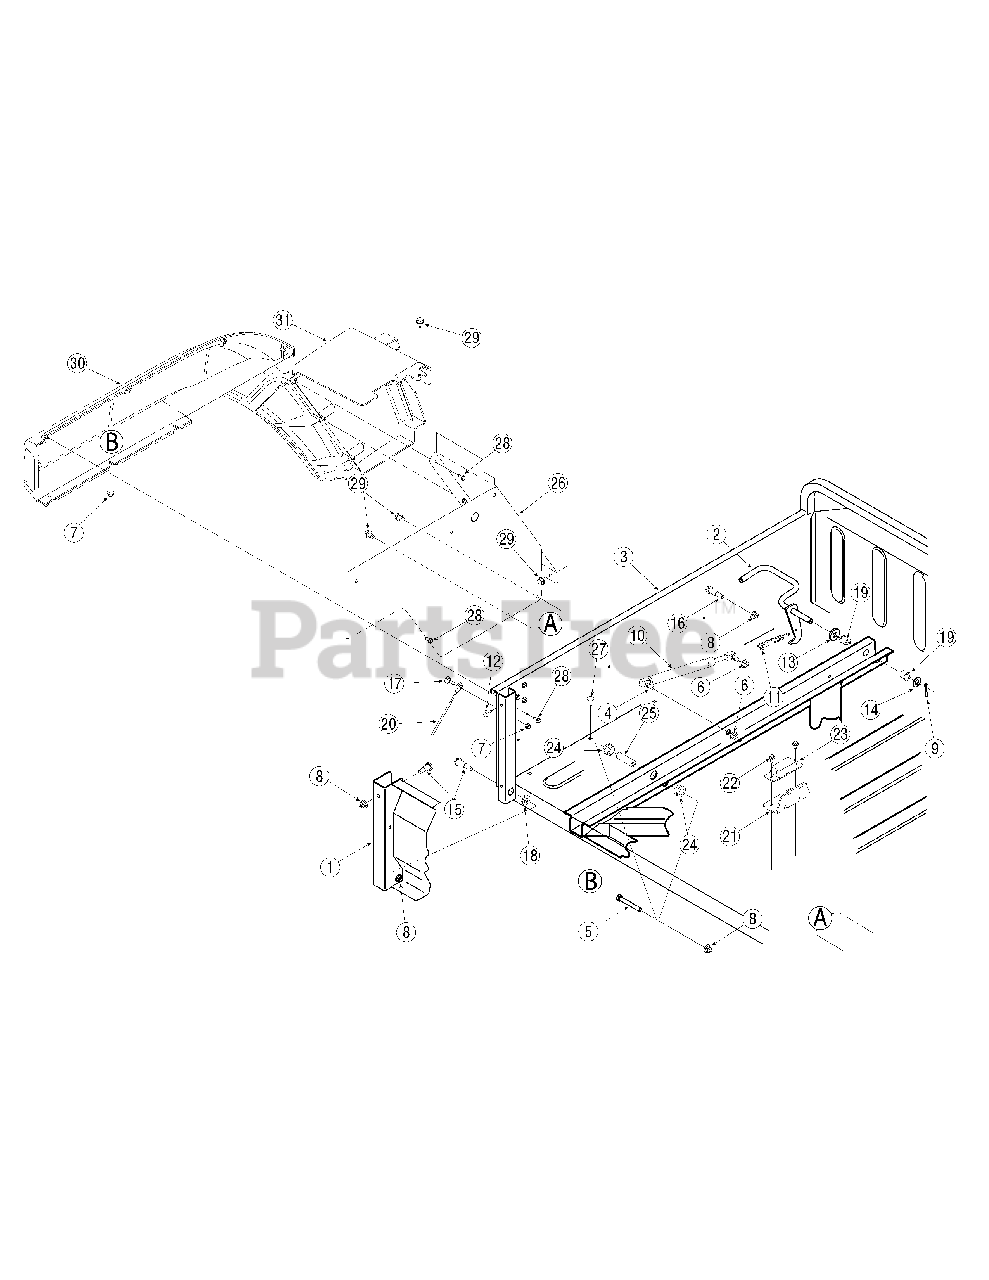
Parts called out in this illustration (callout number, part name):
2	Lvr Asm, bed, latch
4	Stud, ball, 5/16-18
5	Screwew, 3/8-16, 2.75, gr5, std
6	Nut, flglk, 5/16-18, grf, nylon
7	Nut, flglk, 1/4-20, grf, nylon
8	Nut, flglk, 3/8-16, grf, nylon
9	Pin, cot, 5/32, 1.25
10	Spr, gas, 6.91 Stroke
11	Spr, extn, .50 Od X 4.35 Lg
12	Bmpr, .62 Dia. x .3
13	Wash, flat, .531 X 1.25 X .181
14	Wash, flat, .510 X 1.00 X .060
15	Screw, shldr, .50 X .685, 3/8-16
16	Screw, shldr, .50x.925, 3/8-16
17	Screw, shldr, .375x.280, 1/4-20
18	Brg, flg, hex, .506 Id X .590 L
19	Brg, flg, .503 X .689 X .792
20	Cable, lanyard
22	Screw, tt, 1/4-20x.625, hxindwsh,
23	Bmpr, suspn, extn
24	Brg, hex Flng .629 Id
25	Spcr, .390 Id X.625 OD X 2.03 LG
27	Screw, Crg, 1/4-20, .62, Gr2 (not on camo units)
28	Screw, #12-16, .50, Hxindwsh
29	Screw, Tt, 5/16-18, 0.500
30	Fdr, Lh Rear
30	Fdr, Lh Rr, Camo
31	Fdr, Lwr Lh Rear
31	Fdr, Lwr Lh Rr, Camo
